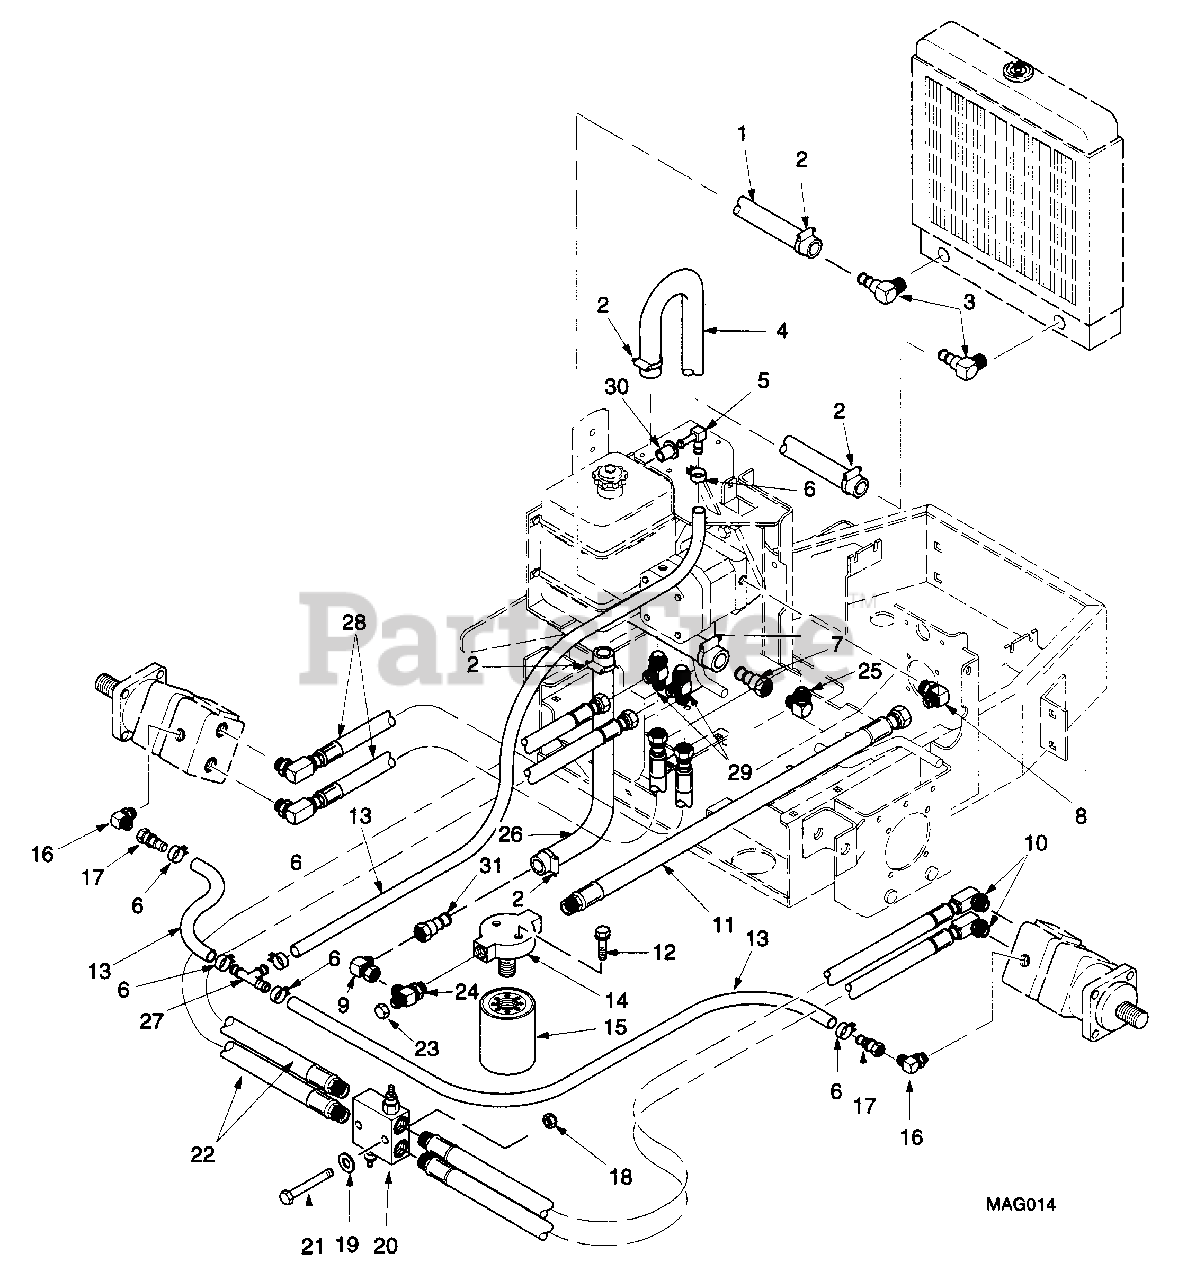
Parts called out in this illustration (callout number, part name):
1	HOSE, PUMP TO OIL COOLER, 5/8 HOSE BARB
2	CLAMP, HOSE
3	ELBOW, 90DEG,
4	HOSE, OIL COOLER/RESERVOIR, 5/8&3/8 HOSE BARB
5	ELBOW, 90DEG
6	CLAMP, HOSE
7	COUPLING, HOSE, 7/8-14 SAE X 5/8 HOSE BARB
8	ELBOW, 90DEG, 1-1/16-12 JIC X 7/8-14 O-RING
9	ELBOW, 90DEG, 3/4 JIC SWIVEL X 3/4 JIC
10	HOSE ASSEMBLY, LEFT MOTOR
11	HOSE ASSEMBLY, PUMP INLET
12	SERR. FL. HEX HEAD CAPSCREW, 1/4-20 X 3/4
13	HOSE, HYDRAULIC, 1/4"
14	FILTER HEAD
15	FILTER, HYDRAULIC
16	ELBOW, 90DEG
17	COUPLING, HOSE
18	HEX NUT, ELASTIC STOP, 5/16-18
19	FLATWASHER, 5/16(.344 X .688 X .065)
20	RELIEF VALVE, DUAL CROSS-OVER
21	BOLT, HEX HEAD, 5/16-18 X 2-1/4
22	HOSE ASSEMBLY, PUMP TO VALVE
23	TUBE CAP, 1-1/16-12
24	TEE, RUN, 3/4 X 3/4
25	ELBOW, 90DEG, 7/8-14 JIC X 7/8-14 O-RING
26	HOSE, RESERVOIR TO FILTER, 3/4
27	TEE, PUSHLOCK, 1/2
28	HOSE ASSEMBLY, RIGHT MOTOR
29	TEE, RUN
30	BUSHING
31	HOSE BARB TO JIC SWIVEL
